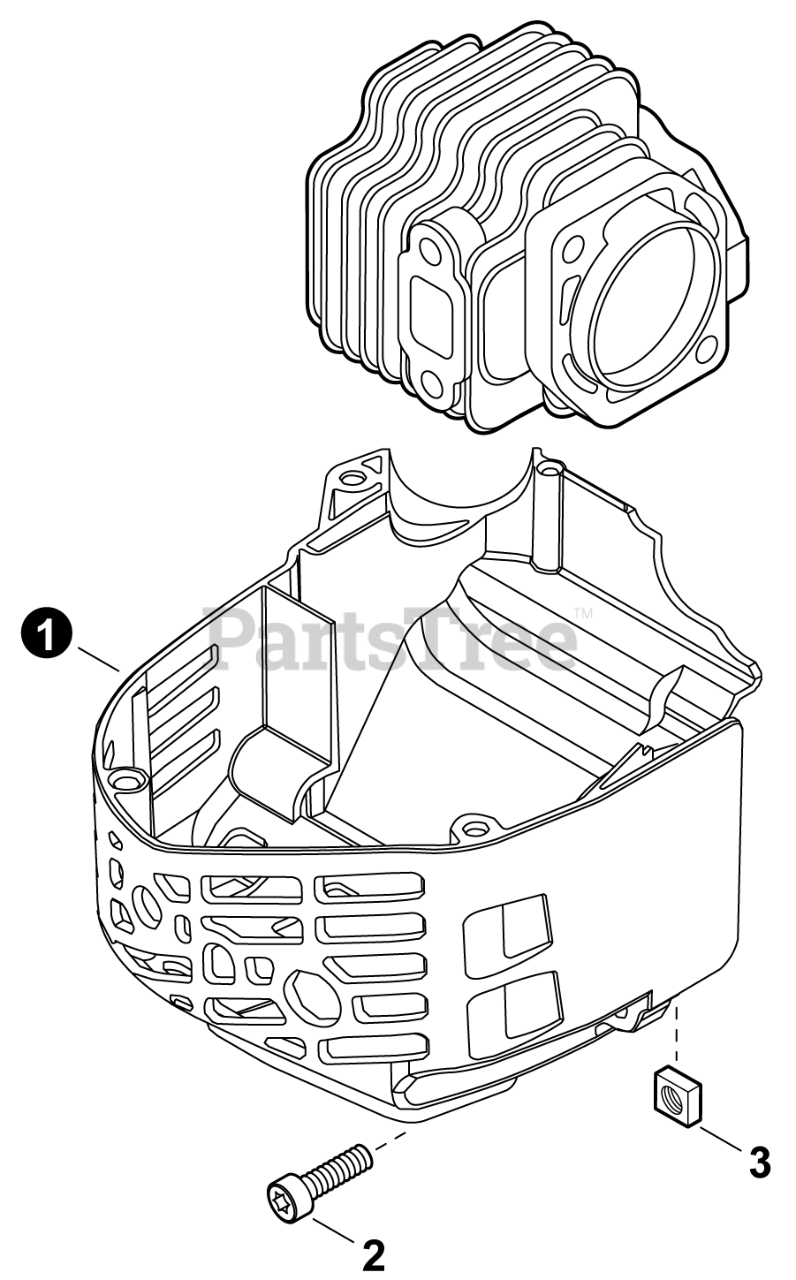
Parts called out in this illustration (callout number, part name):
1	COVER, ENGINE
2	BOLT, TORX 5x16
3	NUT - 5 - SQUARE
